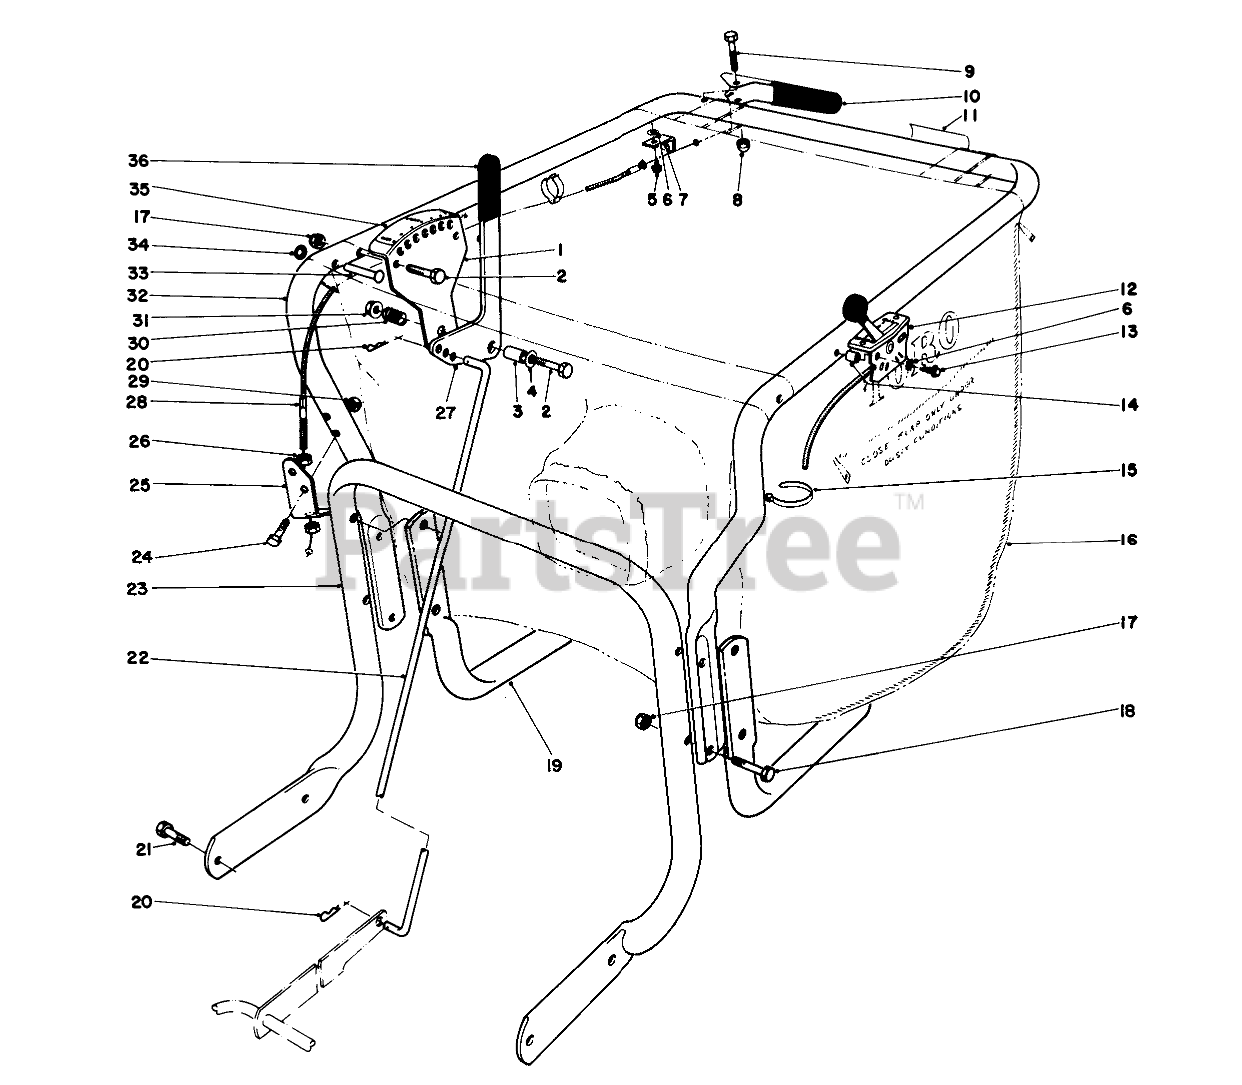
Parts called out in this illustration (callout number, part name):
1	Adjustment Bracket
2	SCREW-HH
3	SPACER
4	WASHER-FLAT
5	SCREW
6	WASHER-LOCK, EXT
7	RETAINING-CLIP
8	NUT-CAP
9	SCREW-HH
10	LEVER W/GRIP
11	TRACTION CONT DECAL
12	THROTTLE CONTROL
13	10-24 X 1 PAN HD SCR
14	SPACER
15	TIE-CABLE
16	Bag-Vacuum
17	NUT-LOCK, CONE
18	SCREW-HH
19	Support-Bag
20	PIN-COTTER
21	SCREW-HH
22	HEIGHT ADJ. ROD
23	HANDLE
24	SCREW-HH
25	MOUNT-BOWDEN, LOWER
26	NUT-KEPS
27	Handle-Adjustment
28	FWD ASSY CABLE
29	NUT-LOCK, CONE
30	SPRING-COMPRESSION
31	NUT-HF
32	HANDLE-UPPER, VACUUM
33	RIVET
34	NUT-PUSH IN
35	HT ADJ DECAL
36	GRIP-HANDLE
